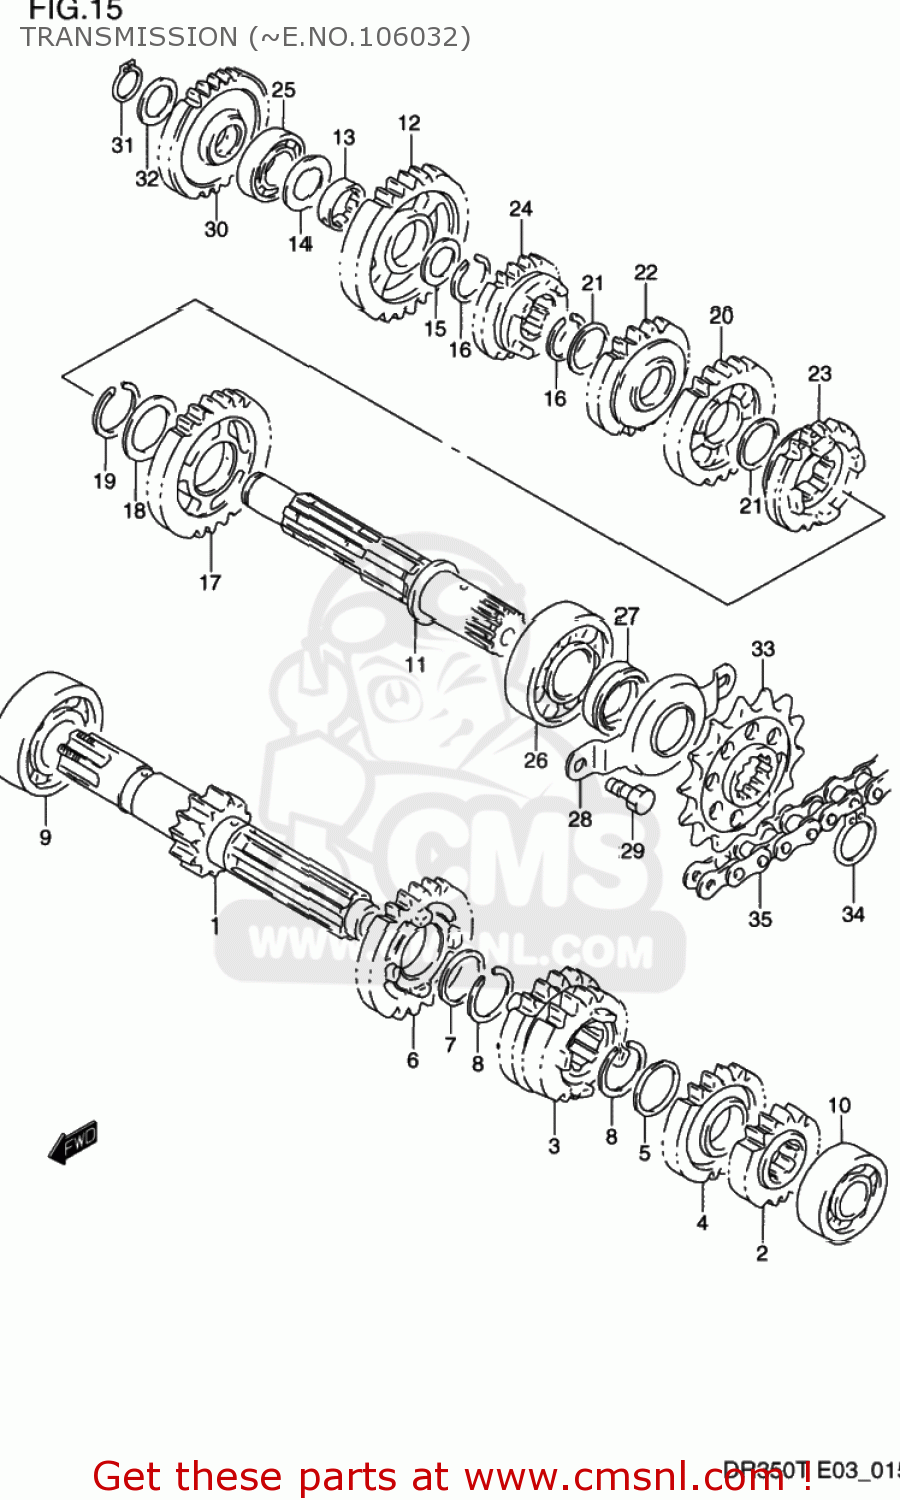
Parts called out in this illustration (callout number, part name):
1	SHAFT,COUNTER
2	GEAR,SECOND DRIVE (NT:15)
3	GEAR,3RD & 4TH DRIVE(NT:18/18)
4	GEAR,5TH DRIVE(NT:21)
5	WASHER
6	GEAR COMP,SIXTH DRIVE
7	SHIM
8	CIRCLIP
9	BEARING
10	BEARING
11	SHAFT COMP,DRIVE
12	GEAR,FIRST DRIVEN (NT:29)
13	BUSH,1ST DRIVEN GEAR
14	WASHER
15	WASHER,THRUST
16	CIRCLIP
17	GEAR,2ND DRIVEN(NT:26)
18	WASHER
19	CIRCLIP
20	GEAR,THIRD DRIVEN
21	SHIM
22	GEAR,4TH DRIVEN(NT:20)
23	GEAR,FIFTH DRIVEN (NT:20)
24	GEAR,SIXTH DRIVEN
25	BEARING(17X42X12)
26	BEARING(22X56X16)
27	SEAL,OIL(22X34X7)
28	RETAINER,DRIVE SHAFT OIL SEAL
29	BOLT
30	GEAR,KICK IDLE
31	CIRCLIP
32	WASHER,THRUST
33	SPROCKET,ENGINE
34	CIRCLIP
35	CHAIN ASSEMBLY,DRIVE
